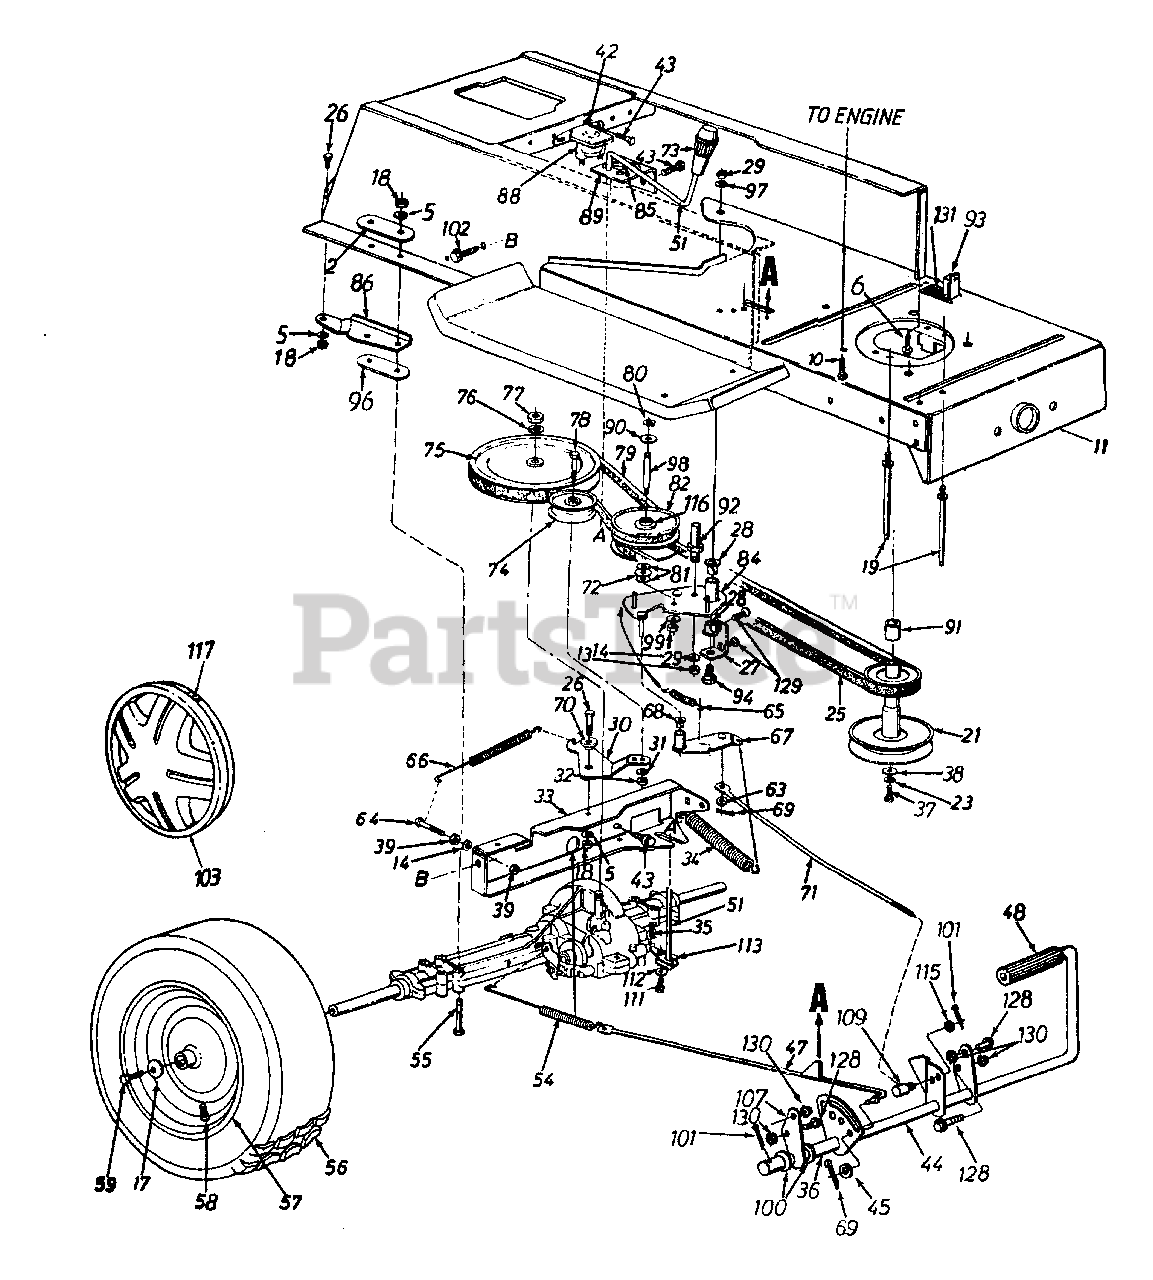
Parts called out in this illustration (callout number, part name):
5	L-Wash. 5/16" I.D.
6	Self-Tap Screw 1/4 x .50
10	Hex TT-Tap Scr. 3/8-16 x 1.5" Lg.
13	Hex Nut 1/4-20 Thd. (Gr. 5)
14	L-Wash. 1/4" I.D.
17	Bell-Wash 345" I.D. x .88"
18	Hex Nut 5/16-18 Thd. (Gr. 5)
19	Belt Guard Stud 4.75" Lg.
21	Engine Pulley
23	L-Wash. 7/16" I.D.
25	Variable-Speed Belt
26	Hex Bolt 5/16-18 x .75" Lg.
27	Bearing Shaft Bracket Ass'y.
28	Flanged Nyliner Brg. 5/8" I.D. x .88" Lg.
29	Hex Nut 3/8-24 Thd.
31	L-Wash. 3/8" I.D.
32	Hex Nut 3/8-24 Thd.
35	Inter. Cotter Pin
36	Spacer .63" I.D.
37	CAP SCREW 7/16-20 X 1.25
38	FlAT WASHER .450
39	Hex Nut 1/4-28 Thd.
42	Ext. L-Wash. 1/4" I.D.
43	Hex Wash. S-Tap Scr. 1/4-20 x .50" Lg.
47	Brake Rod Ass'y.
48	Foot Pad
51	Shift Lever Ass'y.
54	Ext. Spring .59" O.D. x 7.08"
55	Hex Bolt 5/16-18 x 3.5" Lg.
58	Air Valve
59	Hex Bolt 5/16-24 x .75" Lg.
63	Fl-Wash. .34" I.D. x .68" O.D.
64	Hex Bolt 1/4-28 x 1.25" Lg.
65	Ext. Spring
66	Ext. Spring .62" O.D. x 6.12"
68	Flanged Bearing
69	Cotter Pin 3/32" Dia.
70	Shoulder Spacer .27" Lg.
71	Speed Control Link
72	Truss Bearing .56 Dia. x 1.25"
73	Shift Knob
74	Fl-Idler Pulley 3.12" Dia.
75	"V" Pulley
76	Bell-Wash. .56" I.D. x 1.125"
77	Hex Jam Nut 5/16-18 Thd.
78	Hex Bolt 3/8-24 x 1.75" Lg.
79	Variable Speed Belt
80	Snap Ring .56" Dia.
81	Fl-Wash.
82	Variable Speed Pulley Ass'y.
90	Teflon Washer .565" I.D.
91	Spacer 1" I.D. x 1.25" Lg.
92	Belt Keeper 3" Lg.
93	Safety Switch (Clutch)
94	Shld. Bolt 3/8-24 x 3.12" Lg.
96	Transaxle Spacer
97	Bell-Wash. .38" I.D. x .88"
98	Shaft .56" Dia. x 3.875" Lg.
99	Bell-Wash. .39" I.D. x 1.12"
100	Fl-Wash. .64" I.D. x .94"
101	Cotter Pin 1/8" Dia. x 1.25"
102	Hex Wash. Hd. Scr. 5/16-18 x .62"
103	Hub Cap (Gray)
111	Hex Bolt 1/4-28 x .50" Lg.
112	Bell-Wash. .265" I.D. x .75"
113	Shift Lever Link Ass'y.
115	Fl-Wash. .385" I.D. x .62"
116	Needle Brgs.
117	Spring Clip
128	Hex Wash. TT-Tap Scr. 5/16-18x .75"
129	Hex Wash. AB-Tap Scr. 5/16-18x .75"
130	Hex Sems Nut 5/16-18 Thd.
131	Spring Switch
